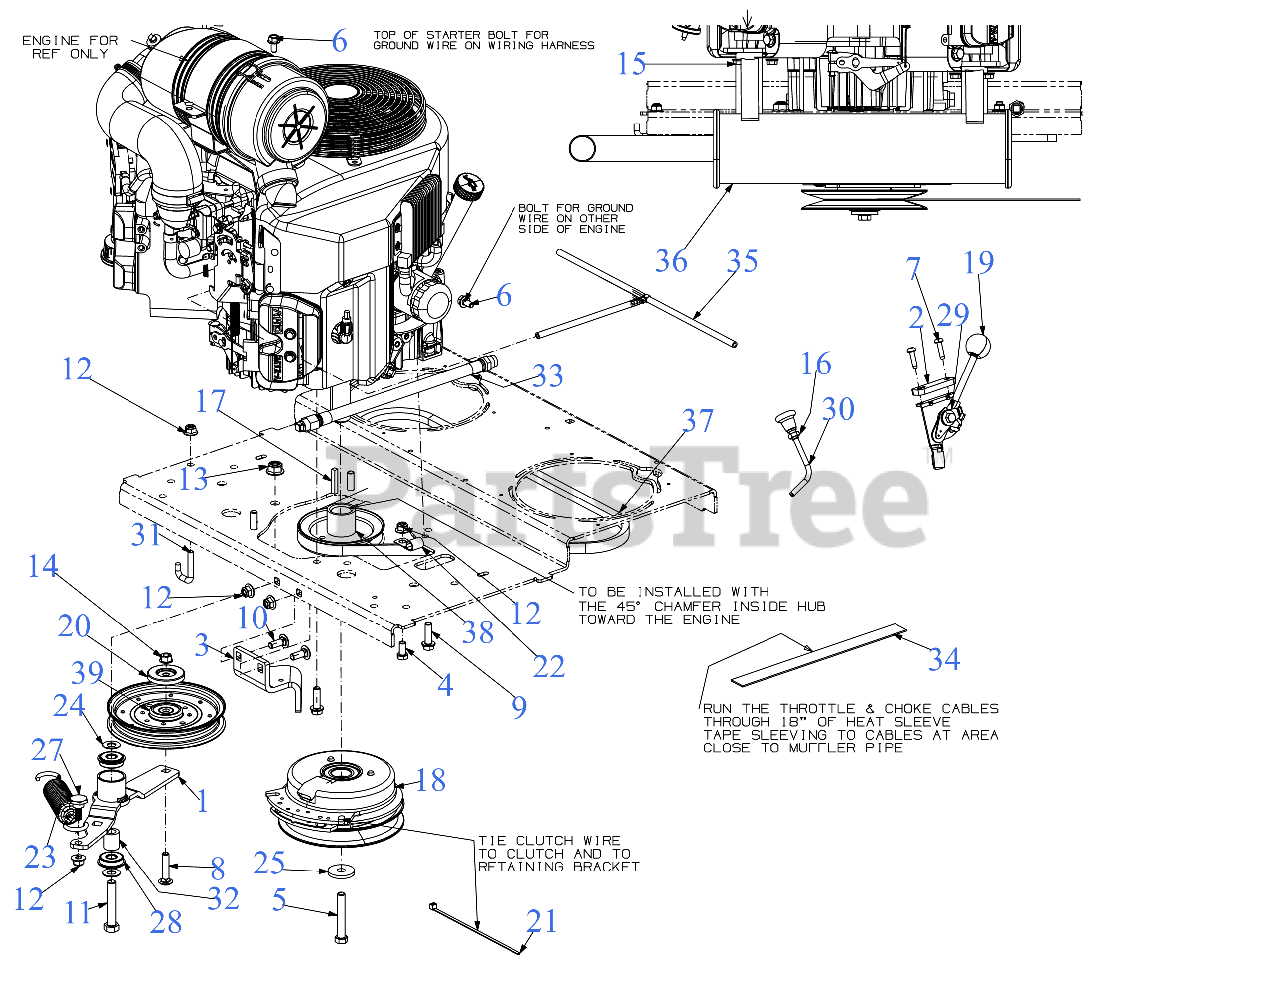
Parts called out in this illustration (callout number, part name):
1	TRANSMISSION IDLER BRACKET
3	CLUTCH RETAINER BRACKET
4	HEX SCREW 3/8-16 x .75
5	SCREW 7/16-20:2.75 GR5
6	SCREW M8 x 1.25 x 16MM GR8.8
7	SCREW 1/4-20 x 1.0
8	CARRIAGE BOLT 3/8-16 x 1.75 GR5
9	SCREW 3/8-16 x 1.25 GR5
10	CARRIAGE BOLT 3/8-16 x 1.00 GR5
11	SCREW 1/2-13 x 2.75 GR5
14	HEX LOCK NUT
15	HEX FLANGE NUT
16	HEX JAM NUT 3/8X24
17	SQUARE KEY 1/4 x 1.50
18	ELECTRIC PTO CLUTCH
20	PULLEY CAP
21	7" CABLE TIE
22	J TYPE CLIP
23	EXTENSION SPRING W/HOOK
24	FLAT WASHER .510X.995
25	FLAT WASHER .45 x 1.5 x .172 HT
27	SHOULDER SCREW .625 x .302 x 3/8-16
28	ROLLER BEARING .5X1.37X.44
29	THROTTLE CABLE 59"
30	CHOKE CABLE
31	ROD SPRING HOOK
32	SPACER 0.51 x 0.88 x 1.00
33	OIL DRAIN HOSE
34	HEAT SHIELD 24"
35	ROLLOVER VENT HOSE ASSEMBLY
36	MUFFLER - KAWASAKI 1000
37	TRANSMISSION BELT
38	PULLEY - PUMP DRIVE
39	IDLER PULLEY
